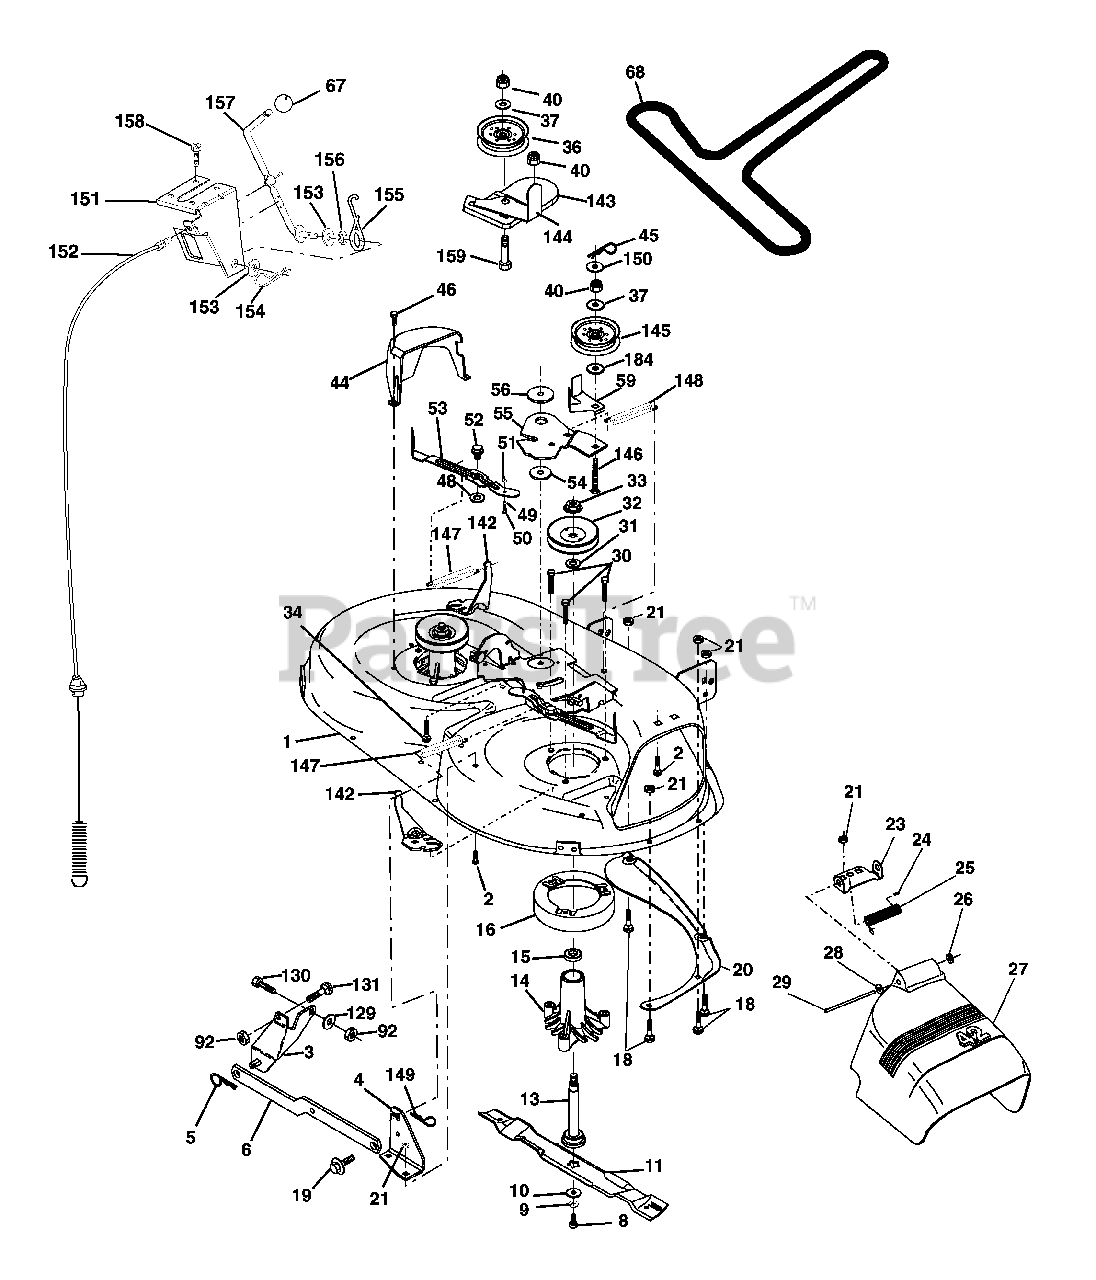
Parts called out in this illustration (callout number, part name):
1	Mower Deck Assembly, 42"
2	Bolt
3	Bracket Asm Fr. Sway Bar 3/42
4	Bracket Asm Deck 42" Sway Bar
5	Retainer Spring
6	Bar Sway Deck
8	Bolt 3/8-24 x 25 Grade 8 patched
9	Washer, Lock
10	Washer, Hardened
11	Blade, 42" Mulching Std
11	Blade, 42" Mulching Premium
11	Blade, 42" Hi-Lift
13	Shaft Assembly, Mandrel, Vented
14	Housing, Mandrel, Vented
15	Bearing, Ball, Mandrel
16	Stripper, Mandrel Deck
18	Bolt, Carriage 5/16-18 x 5/8
19	Bolt, Shoulder
20	Baffle, Vortex
21	Nut
23	Bracket, Deflector Mower 42"
24	Cap, Sleeve 80 x 112 Blk Mower
25	Spring, Torsion, Deflector 2 52
26	Nut, Push Phos & Oil
27	Shield, Deflector 42" Blk
28	Washer 11/32 x 5/8 x 16 Gauge
29	Rod, Hinge 42" 6 75 W/G
30	Screw Thdrol Washer Head
31	Washer, Spacer Mower Vented
32	Pulley, Mandrel
33	Nut, Toplock 9/16 Flange
34	Bolt
36	Pulley, Idler, Flat
37	Washer 13/32 x 13/16 x 16 Gauge
40	Nut
44	Guard, Mandrel, LH
45	Retainer
46	Screw, Thdrol 1/4-20 x 5/8 T
48	Washer, Hardened
49	Roller Assembly, Cam Follower
50	Bolt, Shoulder #10-24 Grade 5
51	Locknut
52	Bolt, Shoulder 5/16-18 UNC
53	Arm Assembly, Pad, Brake
54	Washer, Hardened
55	Arm, Idler
56	Spacer, Retainer
59	Guard TUV Idler
67	Knob
68	V-Belt, 42" Mower
142	Arm Spring Brake Mower
143	Bracket Arm Idler 42"
144	Keeper Belt 42" Clutch Cable
145	Pulley Idler Flat
146	Bolt Carriage Idler
147	Spring Extension
148	Spring Return Idler
149	Retainer Spring Yellow
150	Washer 9/32 x 3/4 x 16 Ga.
151	Bracket Clutch Cable
152	Clutch Cable 42"
153	Washer Flat 3/8" Type B
154	Spring Retainer
155	Spring Retention LVR CLTCH CAB
156	Spacer Clutch Cable
157	Rod Clutch Cable 3/8"
158	Screw Hex Thd Cut 1/4-20 x 1/2
159	Bolt Rdhd Sqn 3/8-16 UNC x 1-3/4
184	Washer 13/32 x 7/8 x 10 Ga.
